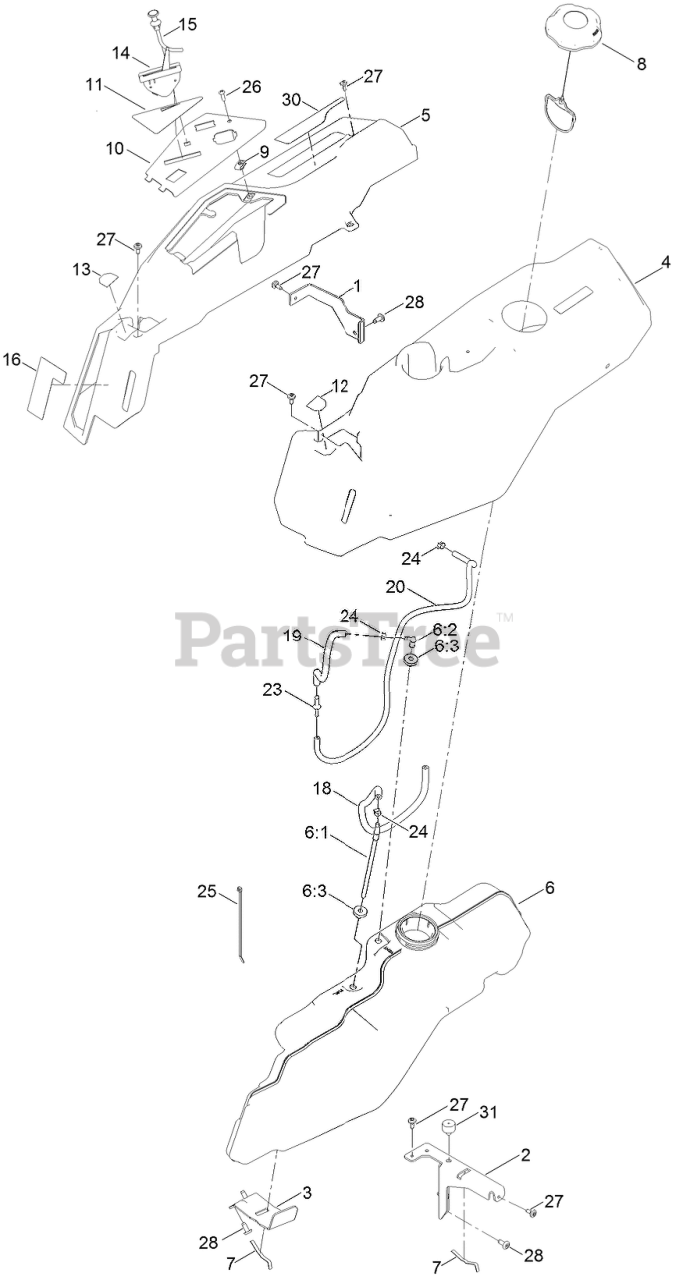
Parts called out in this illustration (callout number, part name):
1	BRACKET-POD
2	SUPPORT-POD, LH
3	SUPPORT-TANK, FUEL
4	POD-LH
5	POD-RH, MYRIDE
6	FUEL TANK ASM
6:1	CONNECTOR-ELBOW, 90 DEG
6:2	FITTING-PLASTIC
6:3	BUSHING
7	SPRING
8	CAP-FUEL, RATCHETING
10	PANEL - CONTROL
11	DECAL-PANEL, CONTROL
12	DECAL-CONTROL LEVER, LH
13	DECAL-CONTROL LEVER, RH
14	CABLE-THROTTLE
15	CABLE-CHOKE
16	DECAL-SMART SPEED
18	HOSE-FUEL
19	HOSE-FUEL
23	ADAPTOR-ORIFICE
24	CLAMP-HOSE
25	TIE-CABLE
26	SCREW-PRH
27	SCREW-SHOULDER
30	DECAL-ADJUSTMENT
31	BUMPER-GROMMET
